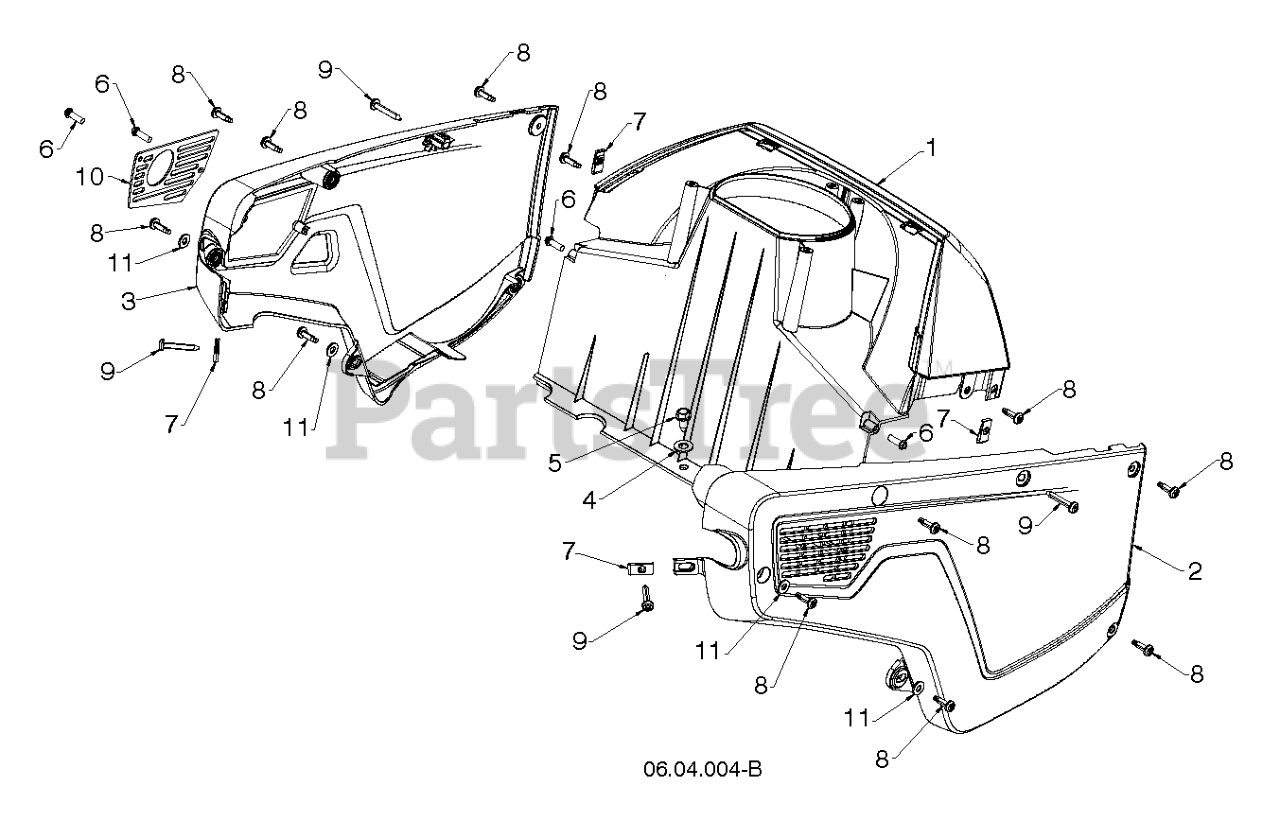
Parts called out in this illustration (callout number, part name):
1	PLENUM.AUGER.SS.SNO.POULAN PRO
2	COVER.NON-DRIVE.SIDE.POUL PRO
3	COVER.DRIVE SIDE.POULAN PRO
4	Washer 13/32 x 1-3/16 x 12 Gauge (AYP part number)
5	BOLT.HEX.HD.WASHER.5/16-18X.75
6	SCREW.HX.13X.750
8	SCREW.PAN.HD.TORX.1/4-20X.750
9	SCREW.1/4-20.PAN.HEAD.TORX.
10	PLATE.EXHAUST.SINGLE.STAGE.SNO
11	Washer 9/32 x 5/8 x 16 Gauge (AYP part number)
